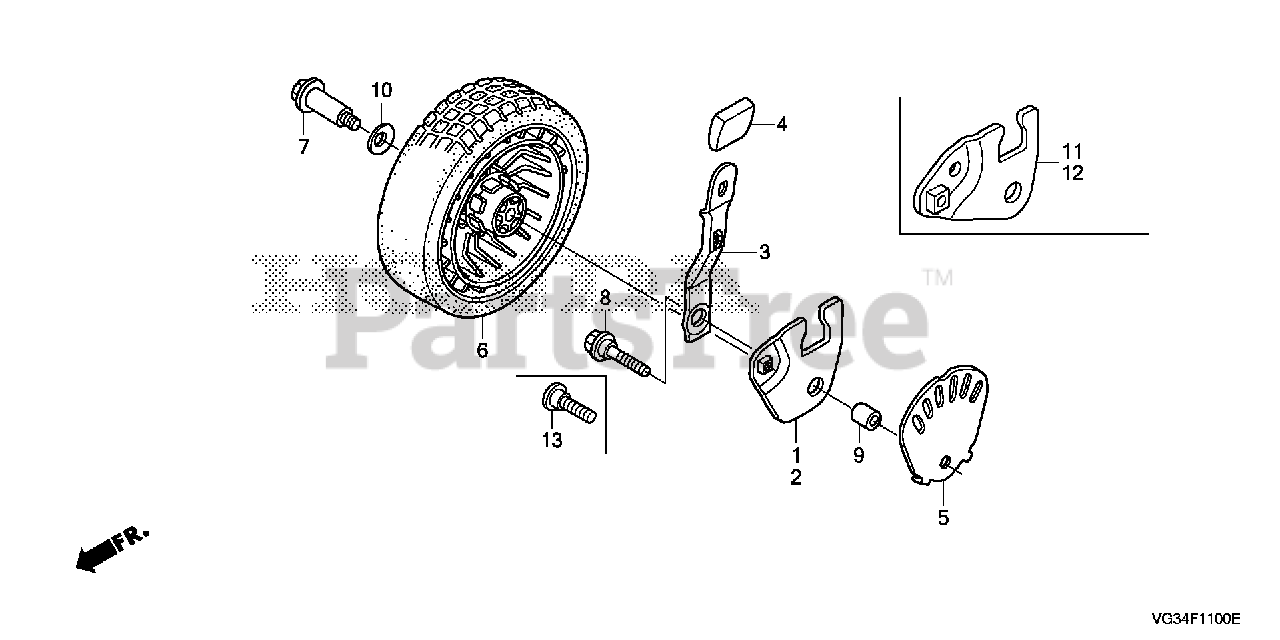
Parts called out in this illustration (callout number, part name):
1	ARM, R. FR. ADJUSTING
2	ARM, L. FR. ADJUSTING
3	PLATE, FR. ADJUSTER
4	GRIP, ADJUSTER *NH105* (MAT BLACK)
5	PANEL, FR. ADJUSTER
6	WHEEL, FR. *NH164* (GRIP GRAY)
7	BOLT, FR. WHEEL SHAFT
8	BOLT, ADJUSTER ARM
9	COLLAR, FR. ADJUSTING
10	WASHER, WHEEL
